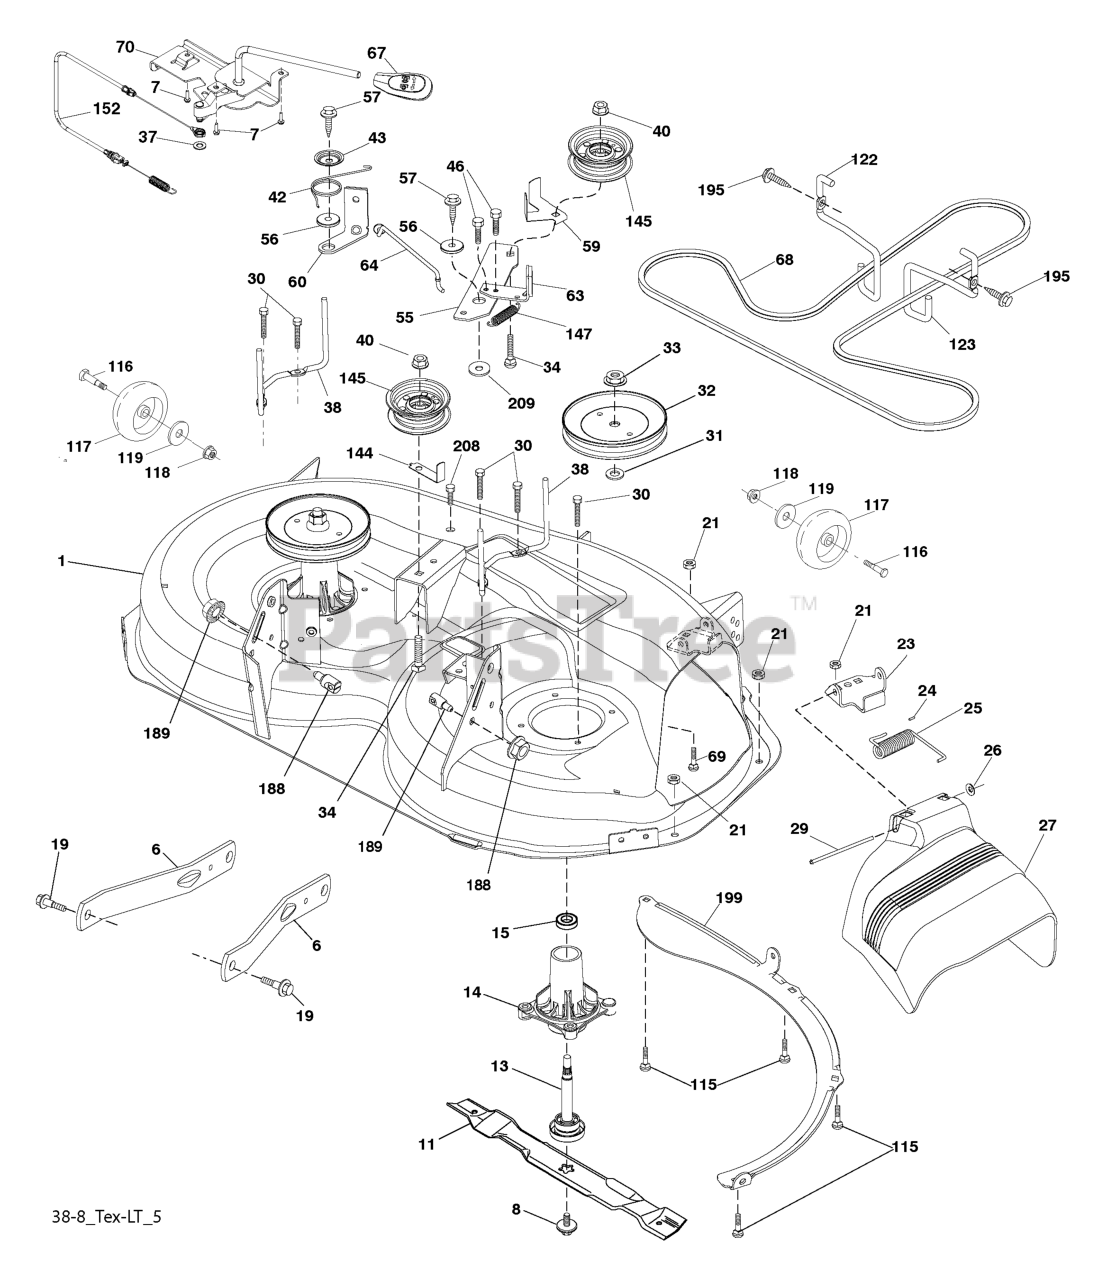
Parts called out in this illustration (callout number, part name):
1	MOWER HOUSING
6	ARM.SUSPENSION.MOWER.R
7	SCREW.#10 X 0.750.BOS
8	BOLT.WASHER.ASM.7/16-2
11	BLADE 38" PREMIUM
13	SHAFT.ASM.MDRL.N/GREASE.38
14	RP.HOUSING.MANDREL.4PT.
19	BOLT.SHOULDER
21	LOCKNUT
23	BRKT.DEFLECTOR.38"2005+
24	CAP-SLEEVE LT
25	SPRING.TORSION.DEFLECT
26	NUT PUSH M
27	SHIELD, DEFLECTOR
29	ROD.HINGE
30	SCREW, WASHER HEAD
31	WASHER.SPACER.MANDREL
32	PULLEY.MANDREL.5.0.PD.38"
33	NUT.FLANGE.LOCK.TOP
34	BOLT.3/8-16X1.50
37	WASHER
38	KEEPER BELT LH MANDREL
40	NUT LOCK FLG 3/8-16 UNC
42	SPRING.TORSION.BRAKE
43	SRPING.TORSION.RETAINE
46	SCREW.1/4-20X5/8
55	IDLER.ARM
56	SPACER.RETAINER
57	SCREW 3/8-16X1
59	GUARD, BELT
60	ARM BRAKE MOWER RH 38"
63	RP ARM.BRAKE.MOWER.38"LH.TEX
64	LINK BRAKE
67	HANDLE.CLUTCH.CABLE.LT
69	BOLT
70	CLUTCH.ASM.MANUAL.LT.PRED
115	BOLT.CARR.5/16-18X5/8.SHORT
116	BOLT M
117	WHEEL.GAGE.HALF.SPOKED
118	LOCKNUT
119	WASHER.5/16.FLAT.STE.STD.
122	KEEPER BELT ENGINE LH
123	KEEPER BELT RH
144	KEEPER BELT
145	PULLEY.IDLER.48"PRIMARY
147	SPRING RETURN
152	CLUTCH CABLE
188	STUD.FASTNER.W/ANTI-ROTATE
189	NUT LOCK HEX FLANGE 5/16-18
195	SCREW, 3/8-16X3/4
199	BAFFLE.VORTEX.FRONT.38"
208	SCREW 3/8-16X1/2
209	WASHER 12/32X2X10GA
